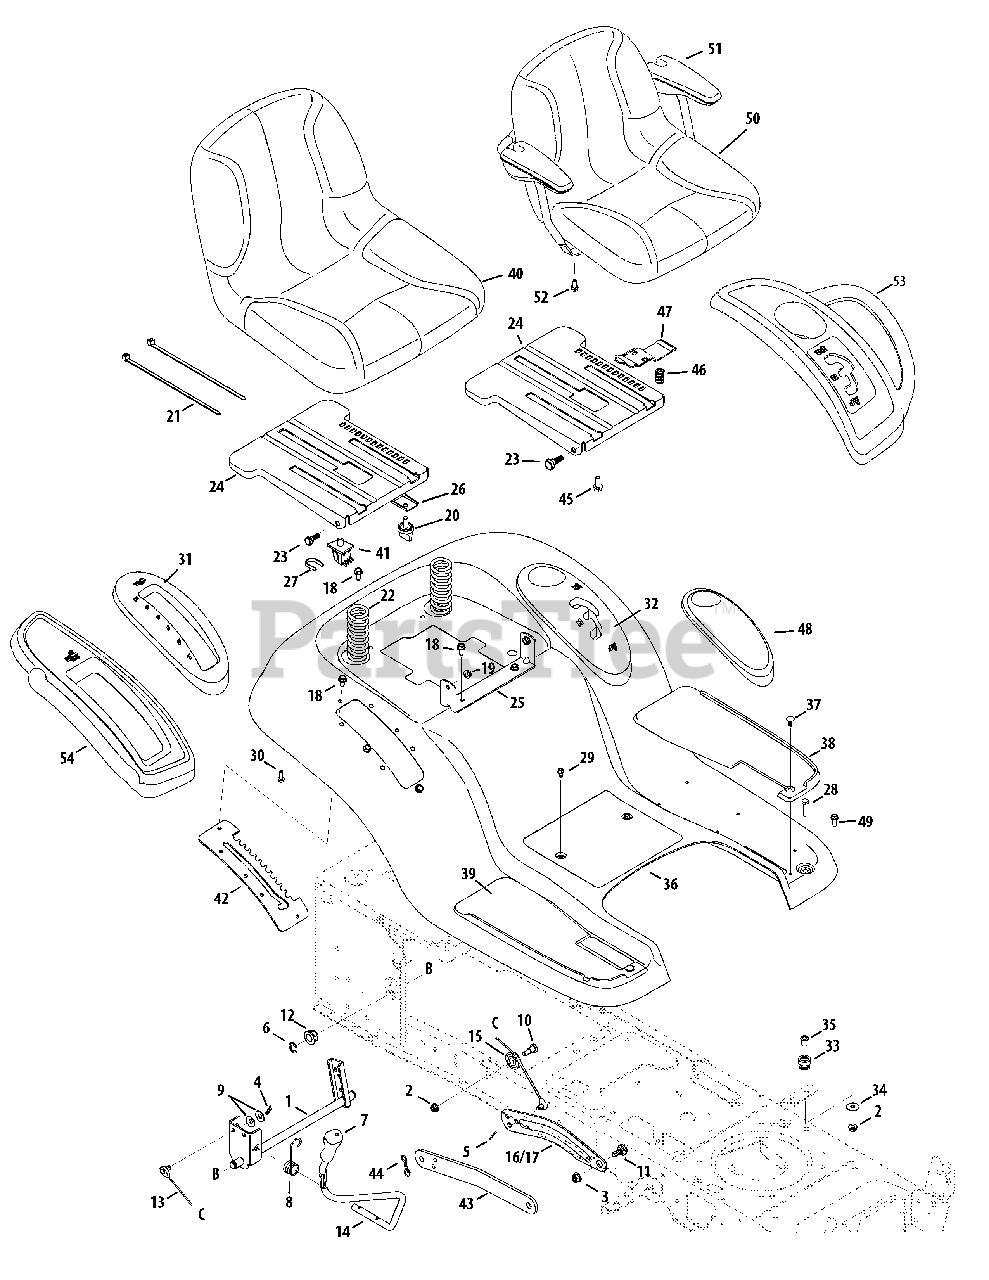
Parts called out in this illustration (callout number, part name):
1	Lift Shaft Ass’y
2	Flange Locknut 5/16-18 Gr. F, Nylon
3	Flange Lock-Nut 3/8-16 Gr. F Nylon
4	Int. Cotter Pin .072 x 1.13" Lg.
5	Bow-Tie Cotter Pin
6	E-ring .625 Shaft
8	Tor sion Spring
9	Cupped Washer .375 ID x .870 OD x .063
10	Shoulder Scr. .437 Dia x .47
11	Shoulder Screw .500 x .25 (46"/50")
11	Shoulder Bolt 3/8-16 x .625 (38"/42")
12	Hex Flange Bearing .630 ID
13	Lift Cable, 16.16
15	Roller Pulley
18	Hex Wash Hd. Tapp Scr. 5/16-18 x .75
19	Hex Flange L-Nut 5/16-18
22	Compression Spring 1.50 x 3.9 x .20
23	Shoulder Screw
26	Seat Bracket, Knob adjustment
27	Switch Retaining Clip
28	Hex Bolt 5/16-18 x 1.25
29	Hex Wash S-Tapp Scr 1/4-20 x .50
30	Hex Tapp Scr 1/4 x .75" Lg.
31	Lift Lever Cover
32	Shift Lever Cover
33	Grommet .4375 ID x .75
34	Flat Washer .344 ID x 1.0
35	Flange Spacer .3125 x .4375 x .625
37	Foot Pad Clips
40	Seat, High Back, Black
40	Seat, High Back, Yellow
42	Lift Bracket 6 positions (w/Electric pto)
44	Bow-Tie Cotter Pin (46")
45	Hex. Hd. Flg. Scr. 3/8-16 x .875
46	Compression Spring .68 x 1.065 x .055
47	Seat adjustment Lever
48	Cover (Hydrostatic Models only)
49	Hex Wash. Hd. Scr. 5/16-18 x .75 Gr. F Nyl.
50	Seat, High Back, Black (w/arm rest option)
51	Arm Rest (incl. R&L)
52	Pan TT Screw 5/16-18 x .75
53	Fender Cover LH
54	Fender Cover RH
